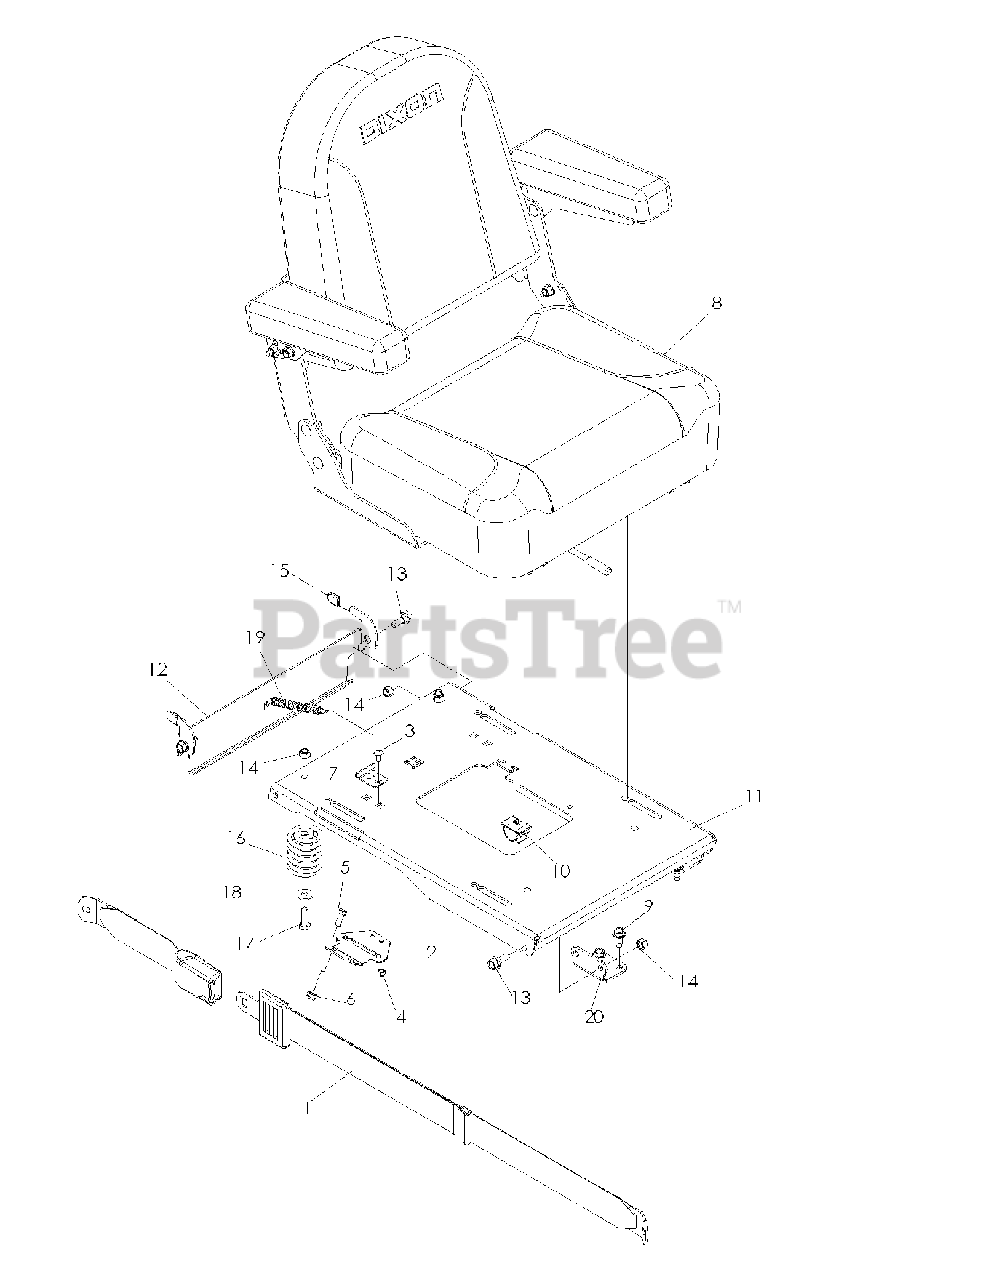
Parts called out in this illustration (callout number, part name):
1	SEAT BELT
2	MOUNT, SEAT BELT
3	RHSNB 5/16-18 X 3/4
4	NUT 5/16 NYLOC
5	HCS 7/16-14 X 1 GR 5 ZD
6	NUT 7/16C CENTERLOCK
7	STOP, SEAT - BLACK
8	SEAT ASM.
9	BOLT 5/16-18 X 3/4
10	PUSH-MOUNT WIRE CLIP
11	PAN, SEAT - BLACK
12	LATCH, SEAT - BLACK
13	SB 5/16-18 HEX HD GD5, BLK ZN
14	NUT 5/16 NYLOC
15	GRIP, VINYL, .09 X .495 X.75
16	SPRING, SEAT
17	HCS 5/16C X 1
18	WASHER 5/16 FLAT
20	PIVOT, SEAT PAN
